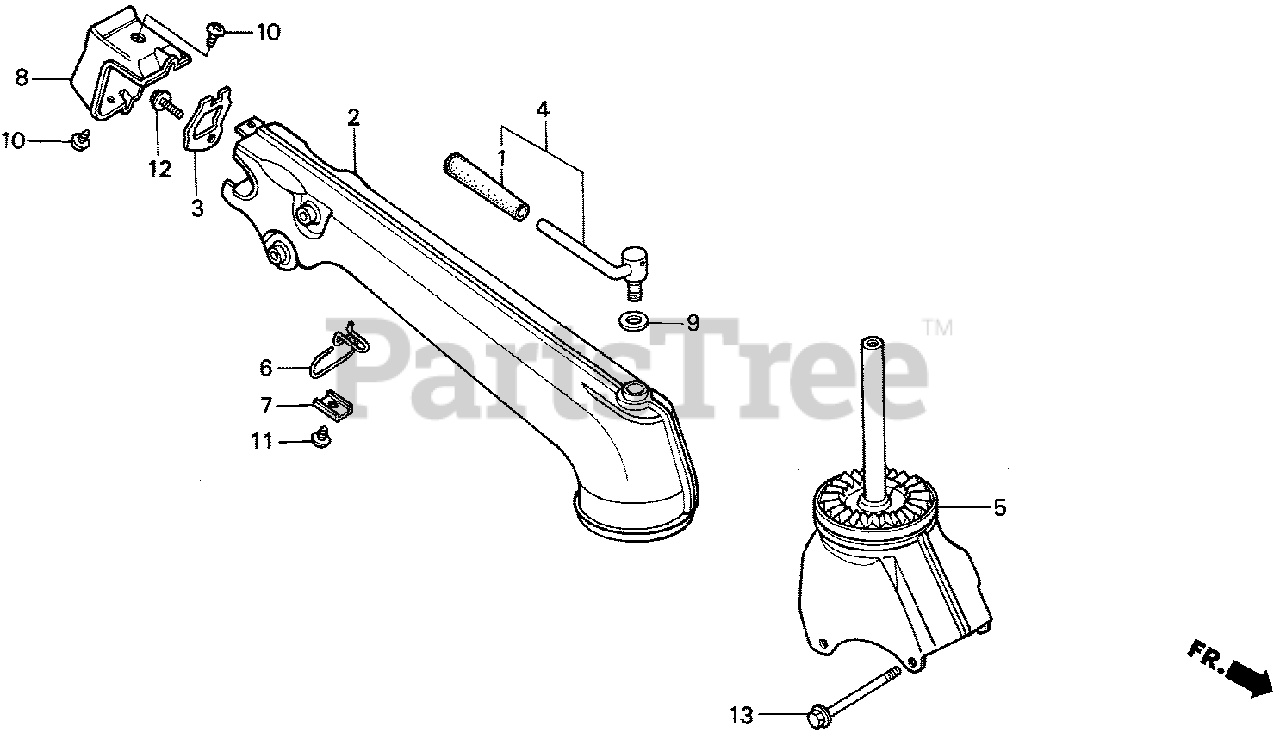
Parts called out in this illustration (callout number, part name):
1	GRIP, LEVER
2	COLUMN, HANDLE
3	PLATE, HANDLE LOCK
4	LEVER, HANDLE ADJUSTING
5	BASE, SWING
6	GUIDE, CABLE
7	BRACKET, CABLE GUIDE
8	DASHBOARD, COLUMN
9	WASHER (10MM)
10	SCREW, TAPPING (5X8) (NOT AVAILABLE)
11	SCREW, TAPPING (5X10)
12	BOLT, FLANGE (6X12)
13	BOLT, FLANGE (10X95)
